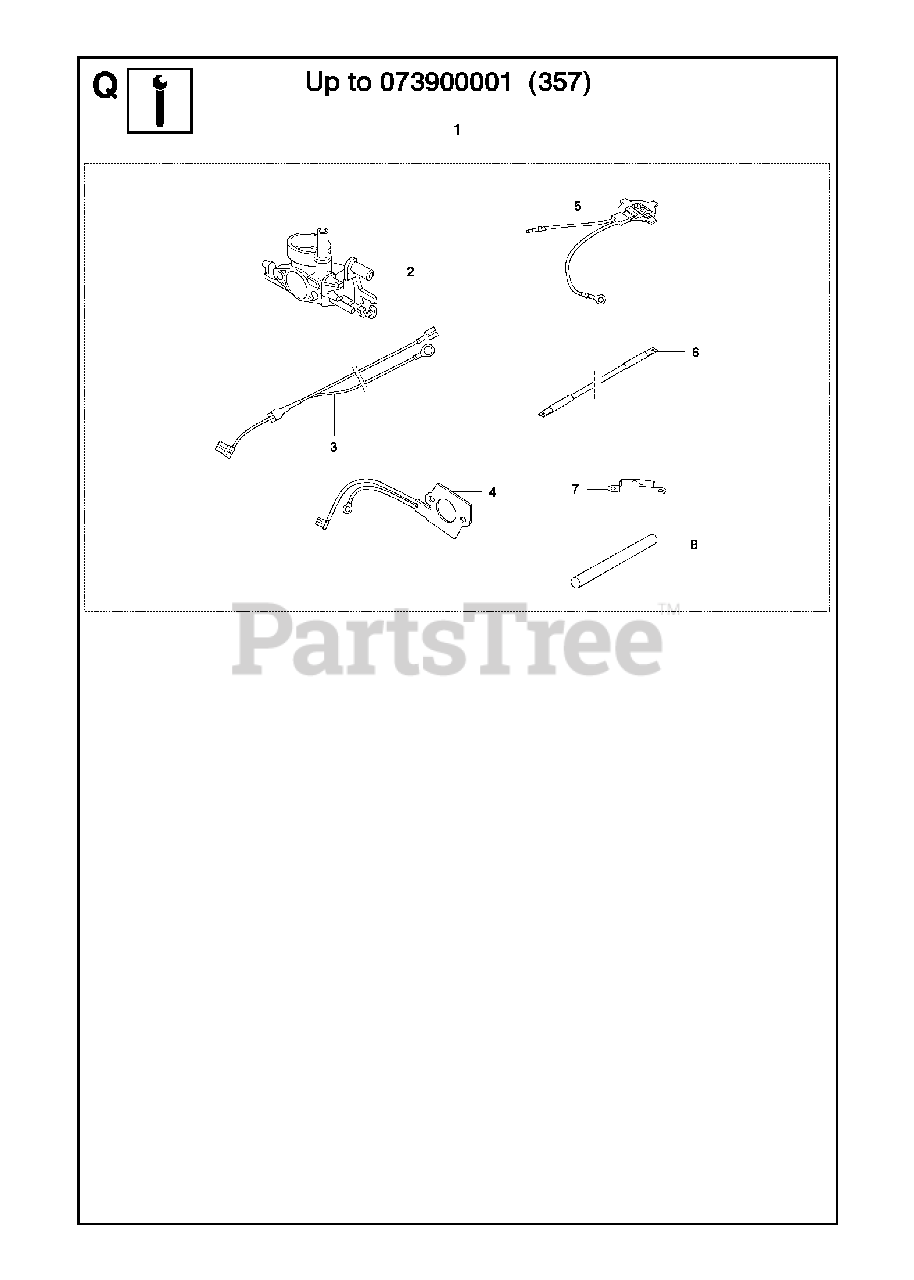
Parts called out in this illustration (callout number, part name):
2	FILTER HOLDER
3	WIRING ASSY
4	Heating Plate
5	THERMOSTAT ASSY
6	WIRING ASSY
7	RETAINER
8	Cable Cover
